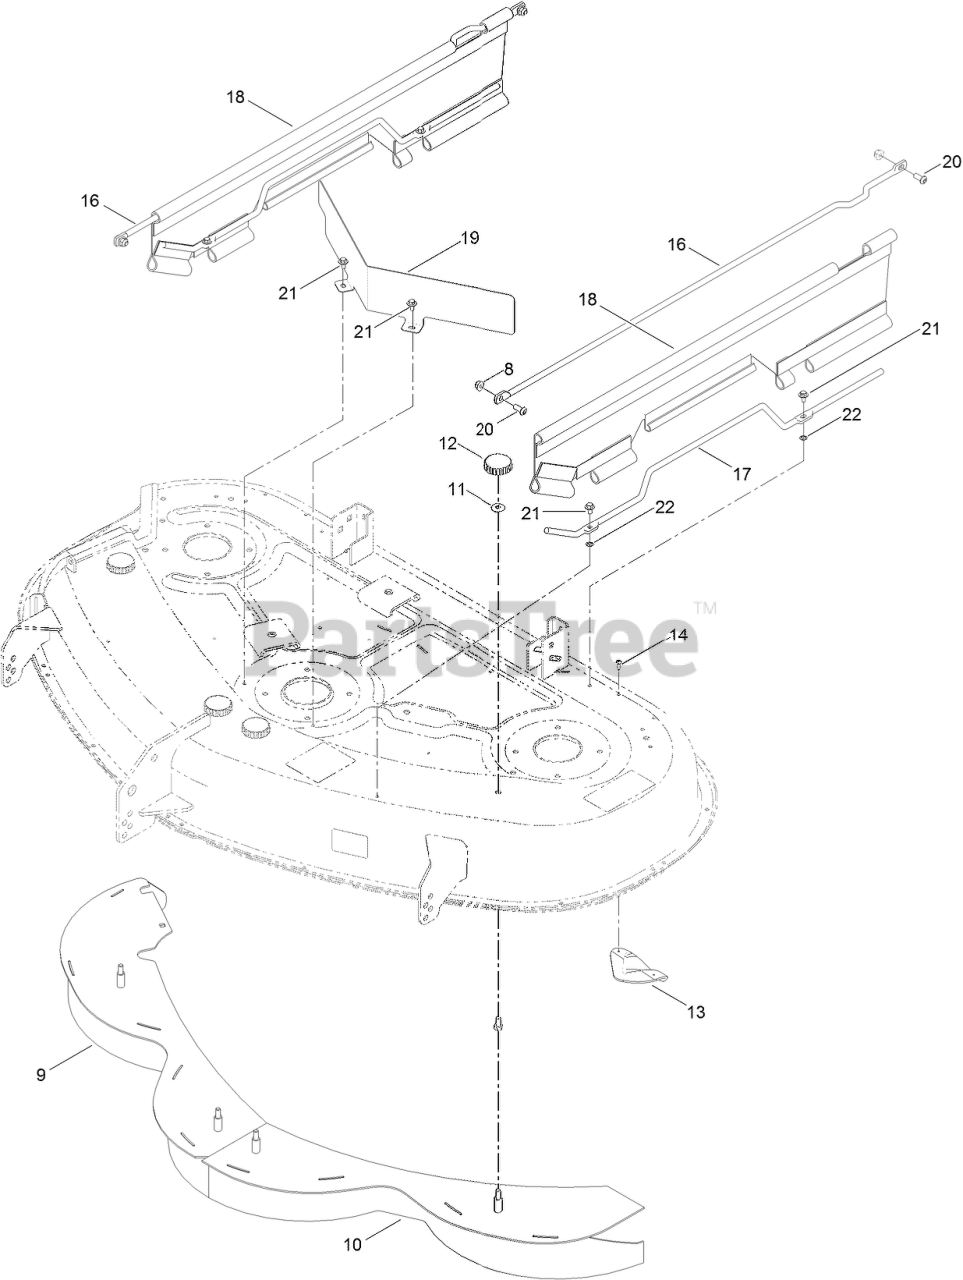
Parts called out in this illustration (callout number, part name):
8	NUT-HF, NI
9	RH BAFFLE ASM
10	LH BAFFLE ASM
11	WASHER-BELLEVILLE
13	PLATE-KICKER
14	SCREW-PPH
16	ROD-SUPPORT, UPPER
17	ROD SUPPORT, LOWER
18	GUARD-SIDE
19	SHIELD-FRONT
20	SCREW-HSBH
21	SCREW-HHFTF
22	NUT-RETAINING
